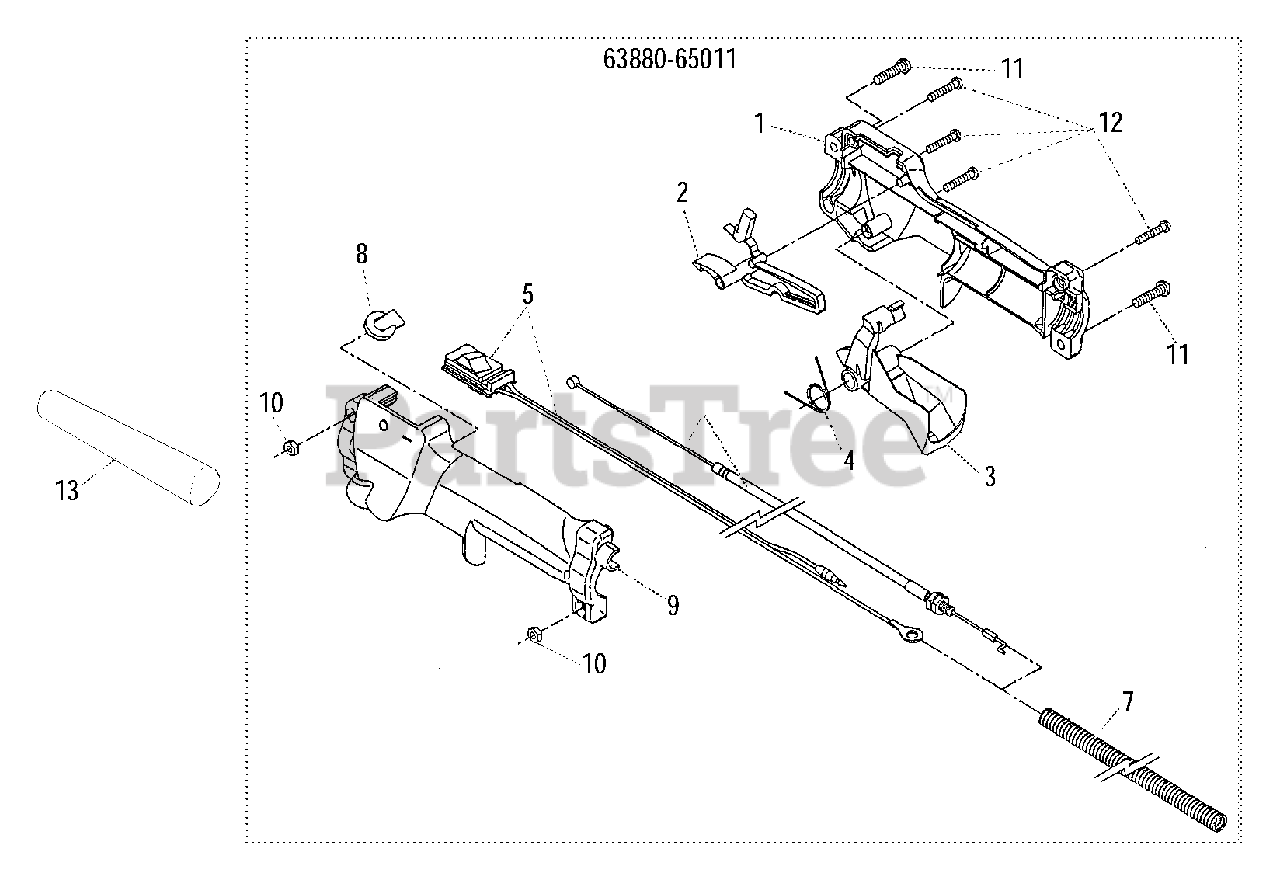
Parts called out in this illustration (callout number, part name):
1	CONTROL HANDLE - RIGHT
2	LEVER, THROTTLE LOCKOUT
3	TRIGGER, THROTTLE
4	SPRING, THROTTLE RETURN
5	SWITCH, ON-OFF
6	CABLE, THROTTLE
7	TUBE, PLASTIC PROTECTIVE
8	PLUG
9	CONTROL HANDLE - LEFT
10	NUT M5
11	SCREW M5×20
12	SCREW, TAPPING M4×20
13	SPACER
63880-65011	THROTTLE CONTROL ASSY
